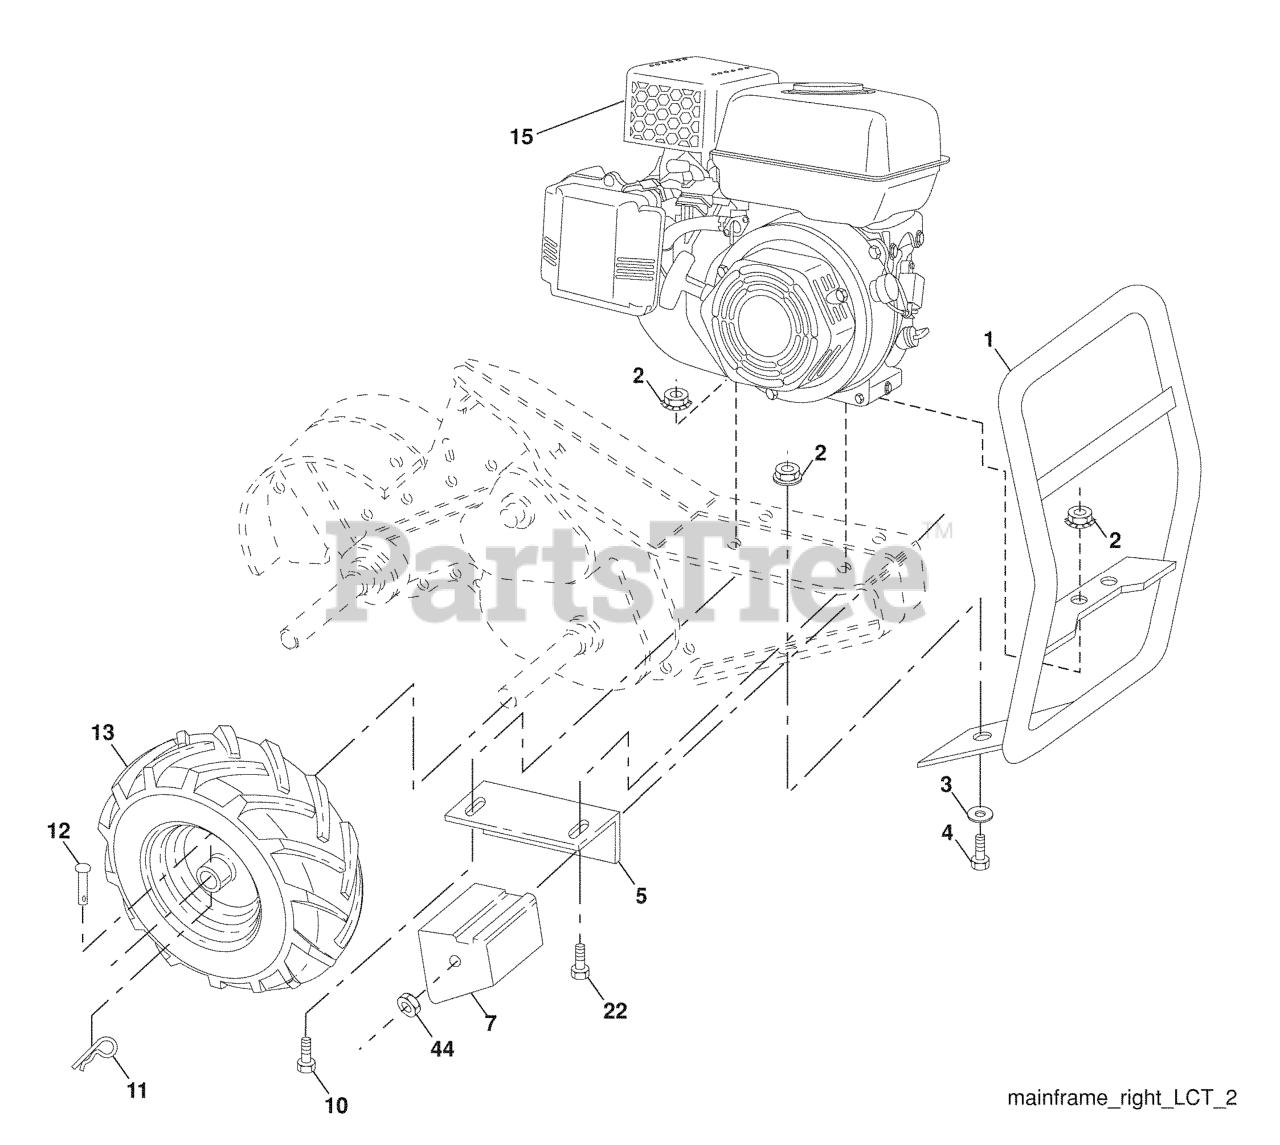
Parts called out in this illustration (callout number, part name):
1	RP.BUMPER.ASM.TILLER.
2	LOCKNUT-FLANGE 5/16-18
3	WASHER
4	BOLT
5	DNO BRACKET RH CRT
7	COUNTERWEIGHT, RH
10	BOLT
11	RETAINER M
12	RIVET,DRILLED
13	TIRE.13X5-6.CHEVRON.TILLER
22	BOLT, HEX 5/16-18X1-3/4
